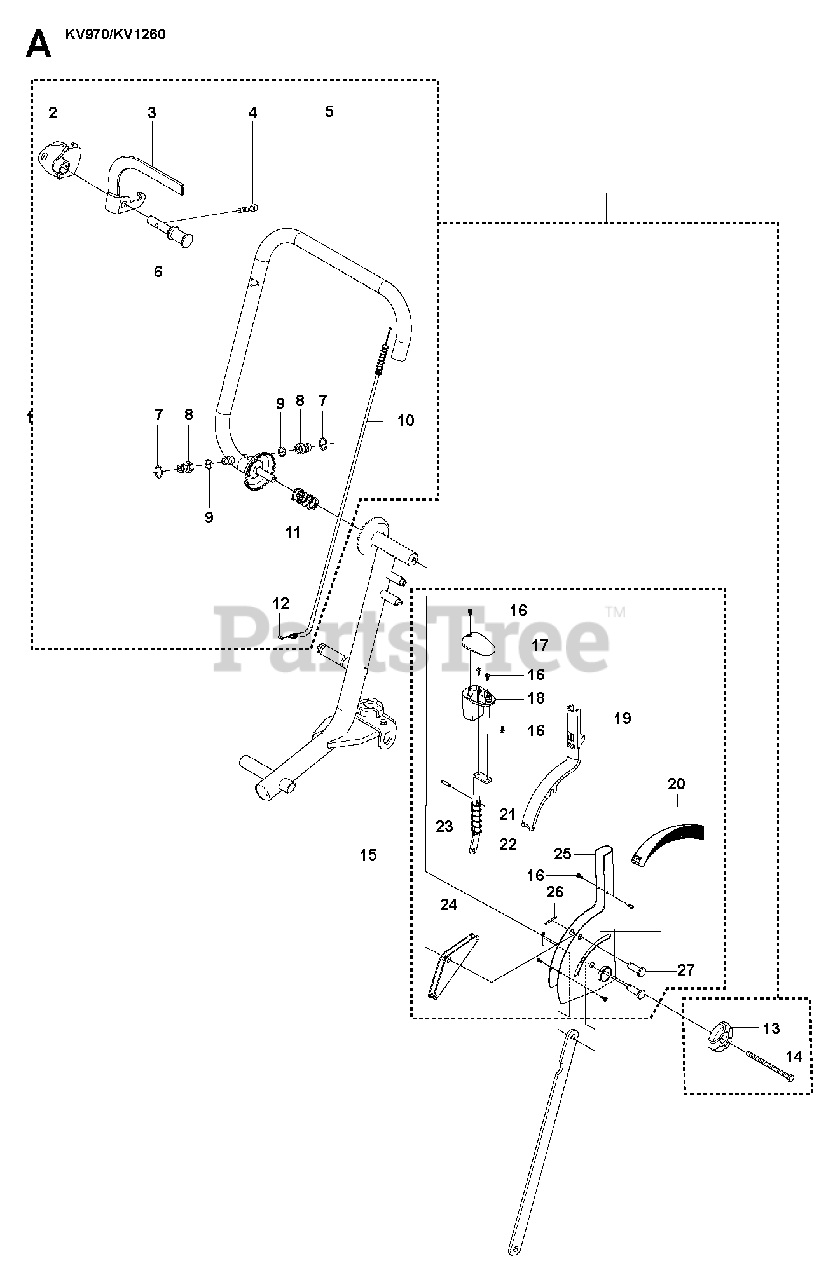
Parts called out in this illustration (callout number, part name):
1	HANDLEBAR ASSYIncl. 2 - 14
3	THROTTLE HANDLE ASSY
11	SPRING THROTTLE CONTROL
13	TURNING KNOB
16	SCREW CRPANT
